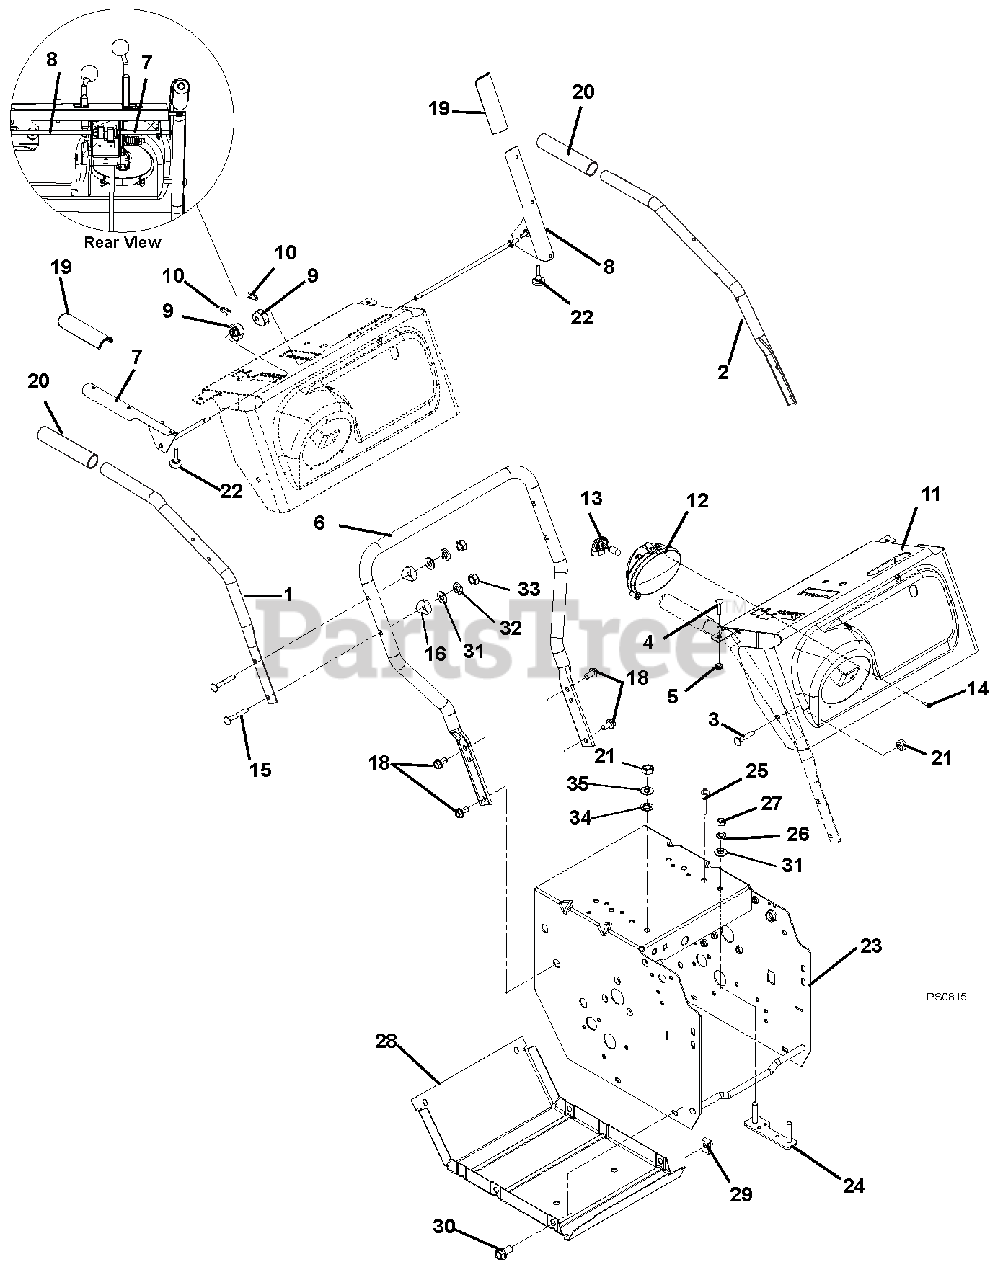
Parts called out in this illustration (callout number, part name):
1	HANDLEBAR, UPPER-RH
2	HANDLEBAR, UPPER-LH
3	@BLT-RDHDSQNK .31-18X1.75 G5YZ
4	BLT-RDHDXLSQNK.25-20X1.25 G5ZC
5	@NUT-LK-TOP-FLG .25-20 YWZC
6	HANDLEBAR, LOWER - DELUXE
7	LEVER, RH-ATTACHMENT
8	LEVER, LH-TRACTION
9	CAM, INTERLOCK
10	PIN, SPRING CLIP
11	CONTROL PANEL W/DECAL
12	LIGHT, HALOGEN ASSY.
13	BULB, LIGHT-HALOGEN 20W
14	SCR-TAP 10-16X.75 HI-LO PPH
15	@BLT-RDHDSQNK .31-18X2.25 G5YZ
16	SPACER, HANDLEBAR
17	KNOB - WING .312-18 UNC
18	BLT-SERHFWH .38-16X.75 YWZC
19	GRIP, CLUTCH LEVER, LH AND RH
20	HANDLE GRIP
21	@NUT-LK-CTR .31-18 YWZC
22	BUMPER, RUBBER - PULL MOUNT
23	WELDMENT, FRAME
24	STRAP, ENGINE BOLT-LARGE BRIGG
25	RVT-POP .187 YZ
26	WSHR-LK .312X.097 HVY YWZC
27	@NUT-HEX .31-18 YWZC
28	COVER, BOTTOM
29	NUT-RTNR .25-20X.56
30	BLT-HEX .25-20X.75 HWH YZ GR5
31	@WSHR-FL-STL.38X.875X.083 YWZC
32	@WSHR-LK .31X.078 REG YWZC
33	@NUT-LK-NYL .312-18 YWZC
34	WSHR-LOCK INT .31 YWZC
35	@WSHR-FL-STL.344X.688X.065YWZC
